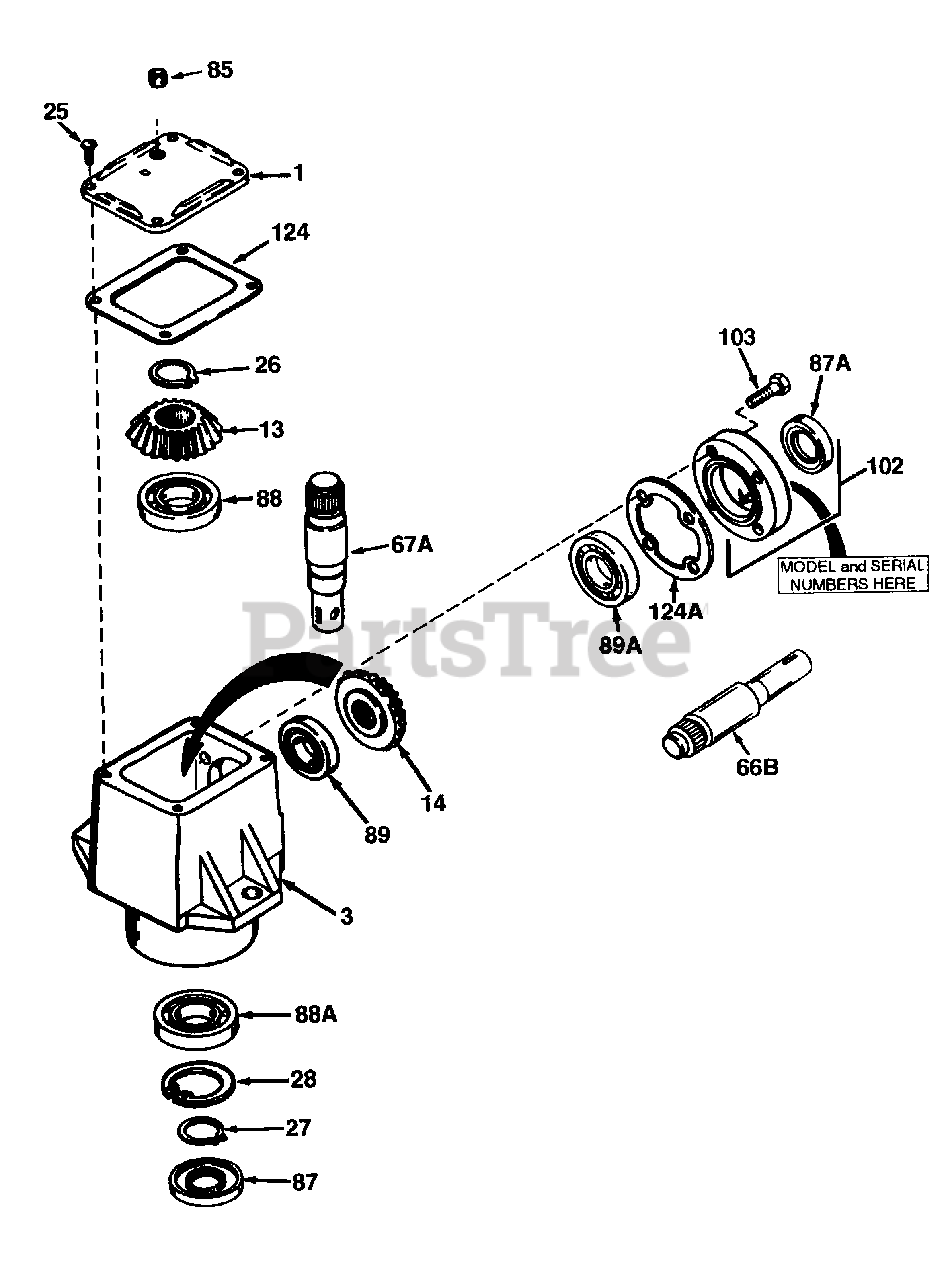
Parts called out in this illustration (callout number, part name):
1	Right Angle Drive Head Cover
3	Right Angle Drive Housing
13	Bevel Gear
14	Bevel Gear
25	Screw, 10-24 x 1/2"
26	Retaining Ring
27	Retaining Ring
66B	Input Shaft
67A	Output Shaft
85	Pipe Plug, 1/8-27
87A	Oil Seal 7/8"
88	Ball Bearing
88A	Ball Bearing
89	Ball Bearing
89A	Ball Bearing
102	Retainer Cap & Seal
103	Bolt, 1/4-20 x 7/8"
124A	Retainer Gasket
